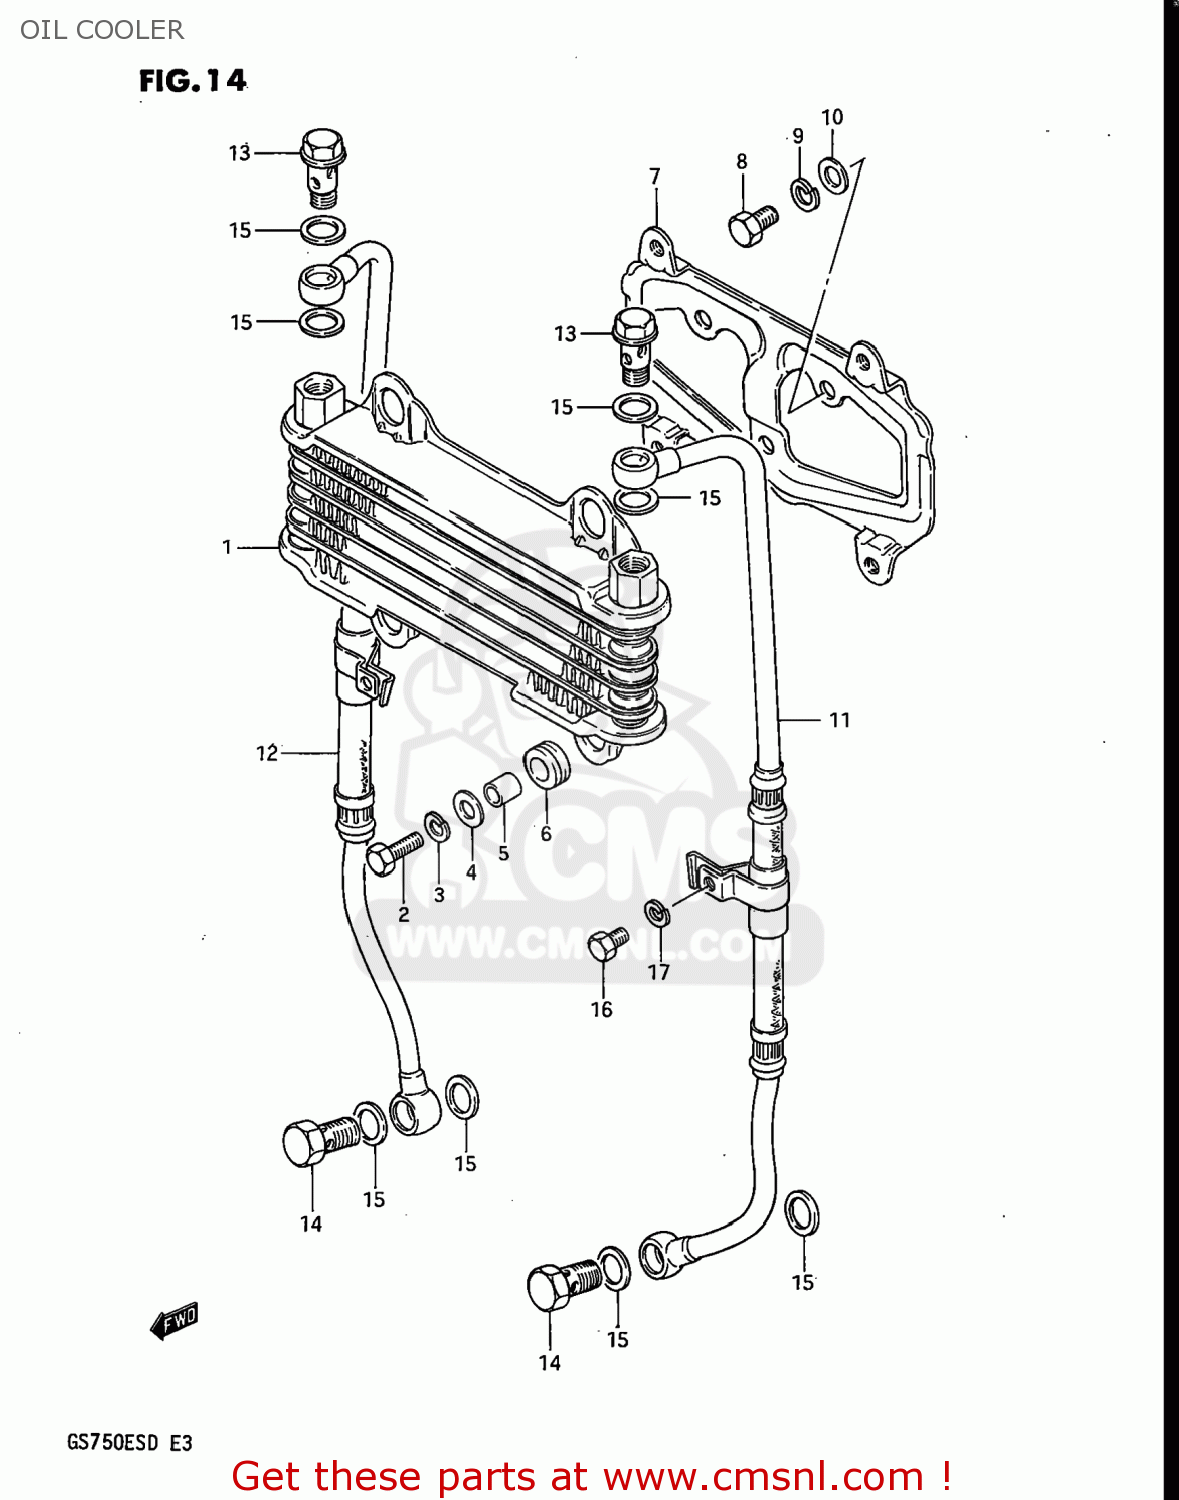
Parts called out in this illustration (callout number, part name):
1	COOLER ASSEMBLY,ENGINE OIL
2	BOLT
3	LOCK WASHER
4	WASHER (6.5X18X1.6)
5	SPACER (6.8X10X10)
6	CUSHION
7	BRACKET,OIL COOLER
8	BOLT
9	LOCK WASHER
10	WASHER,8.5X16X
11	HOSE,ENGINE OIL,LEFT
12	HOSE,ENGINE OIL,RIGHT
13	BOLT UNION
14	BOLT UNION
15	GASKET(14X20X1.5) (NAS)
16	BOLT
17	LOCK WASHER
